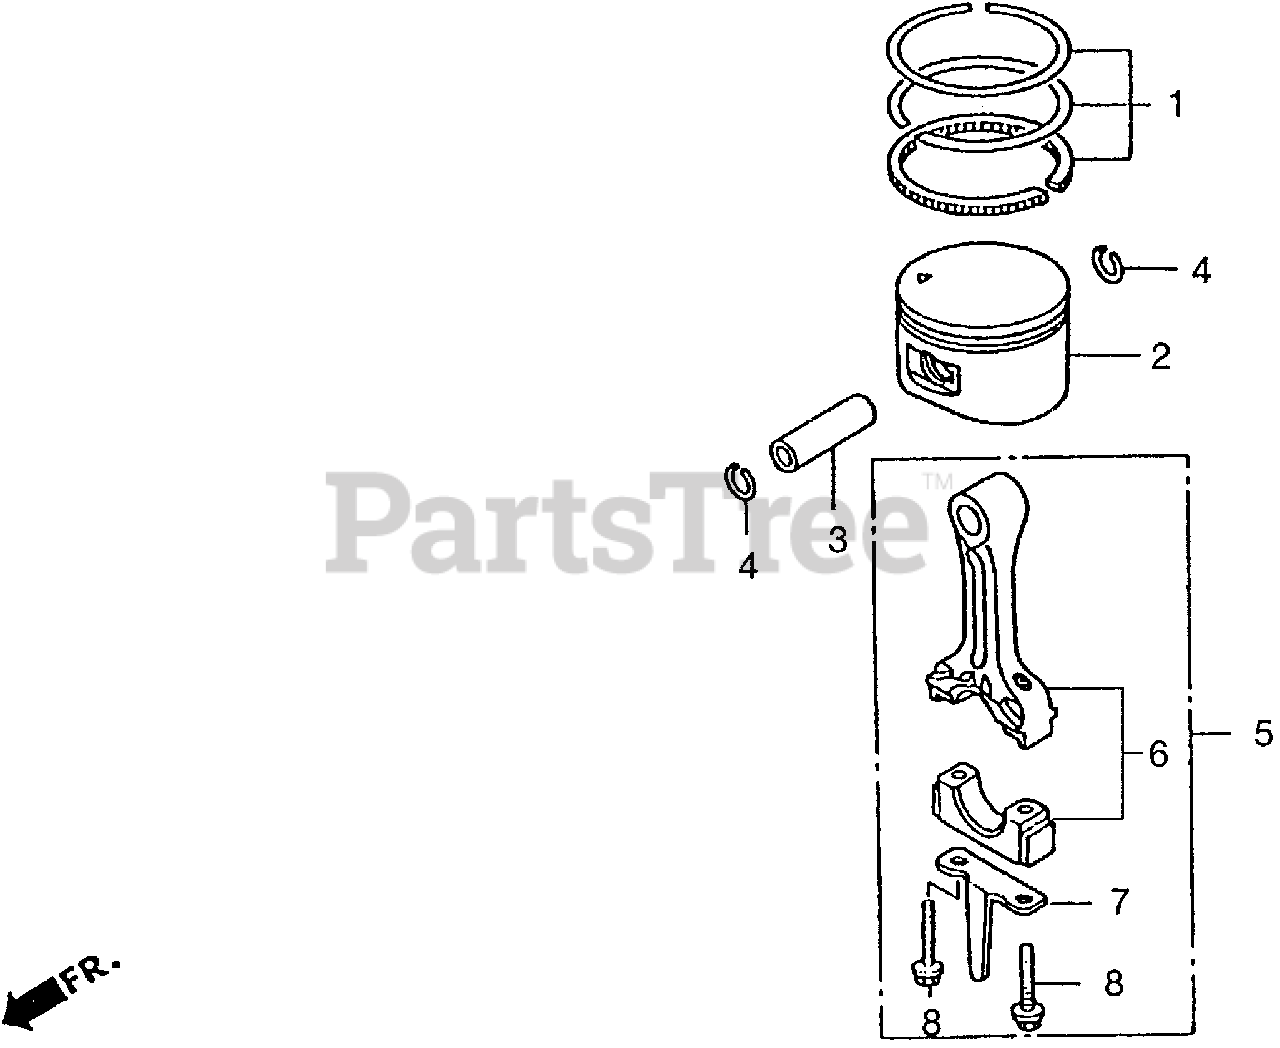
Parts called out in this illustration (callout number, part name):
1	RING SET, PISTON (STD)
2	PISTON (STD)
2	PISTON
3	PIN, PISTON
4	CLIP, PISTON PIN (10MM)
5	ROD ASSY., CONNECTING
7	DIPPER, CONNECTING ROD
8	BOLT, CONNECTING ROD
